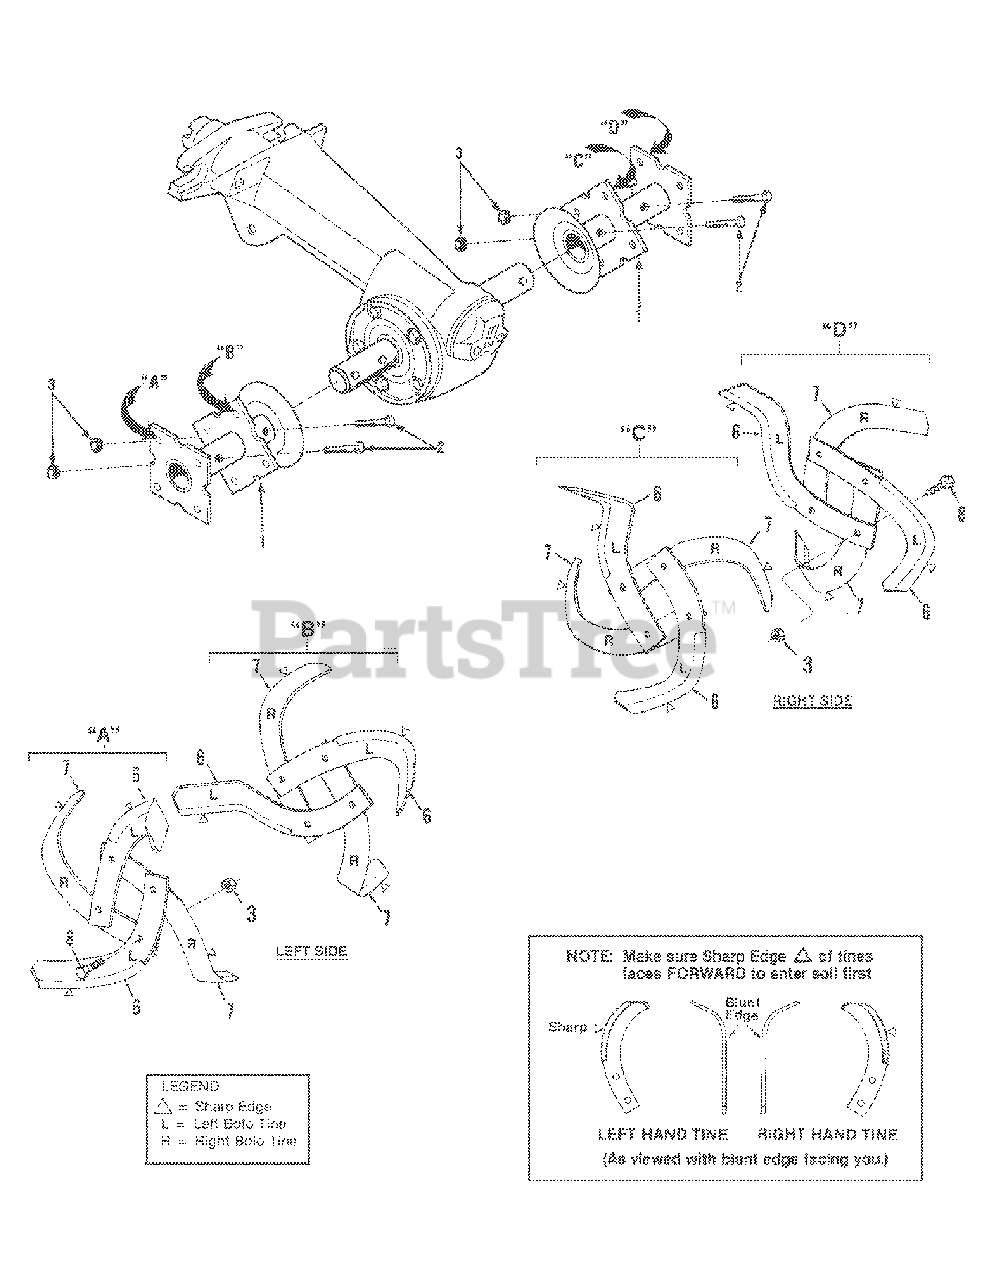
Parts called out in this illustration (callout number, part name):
1	Tine Holder-welded steel, fits left or right sides
2	Bolt-hex hd., 3/8-16 x 2"
3	Locknut-hex, 3/8"-16
6	Bolo Tine-single, left hand. Tine is stamped either "EL" or AL"
7	Bolo Tine-single, right hand. Tine is stamped either "EL" or AL"
8	Bolt-hex hd., 3/8-16 x 1"
